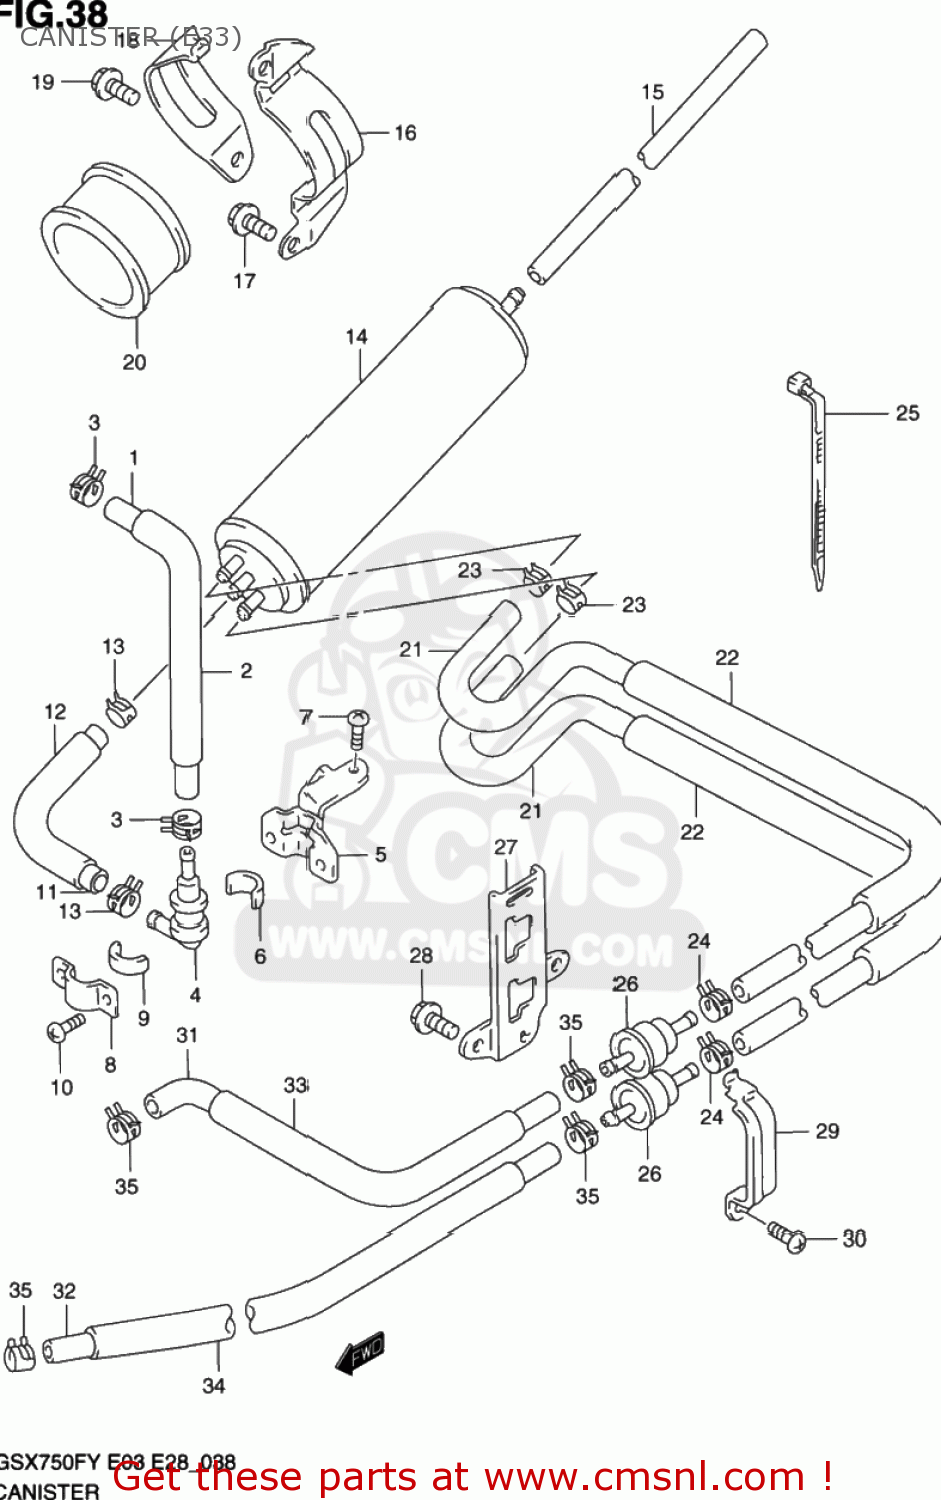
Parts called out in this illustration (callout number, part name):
1	HOSE(5.4X11.4X600)
2	PROTECTOR(14.5X15.5X600)
3	CLIP
4	VALVE,FUEL TANK BREATHER
5	PLATE,BREATHER VALVE
6	CUSHION
7	SCREW
8	PLATE,FUEL TANK BREATHER NO.2
9	CUSHION
10	SCREW 6X12
11	HOSE,VALVE & CANISTER CHARGE
12	PROTECTOR(14.5X15.5X600)
13	CLIP
14	CANISTER ASSY,CHARCOAL
15	HOSE(7X12X600)
16	BRACKET,CANISTER MOUNTING
17	BOLT
18	HOLDER,CANISTER
19	SCREW 6X12
20	CUSHION,CANISTER
21	HOSE,CSTR & PURGE VALVE
22	PROTECTOR(14.5X15.5X600)
23	CLIP
24	CLIP
25	CLAMP(L:125)
26	VALVE,CANISTER PURGE
27	BRACKET,CANISTER PURGE VALVE
28	BOLT
29	HOLDER,CANISTER PURGE
30	SCREW
31	HOSE,CARB & PURGE NO.1
32	HOSE,CARBURETOR & PURGE NO.2
33	PROTECTOR(14.5X15.5X600)
34	HOSE
35	CLIP
